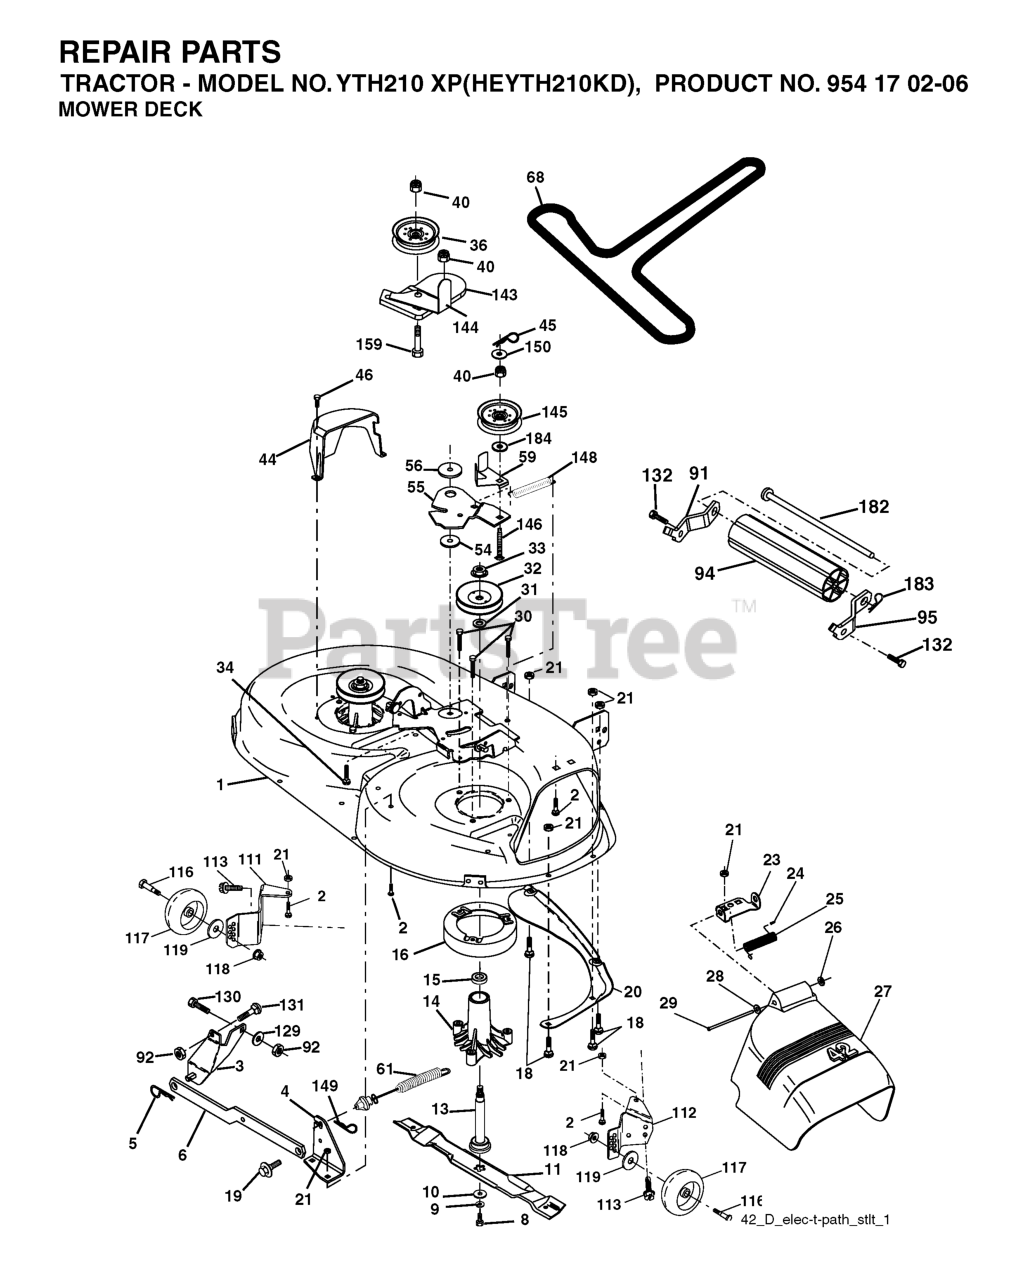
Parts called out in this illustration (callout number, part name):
1	42" DECK KIT
2	RP BOLT 5/16-18 X3/4 ZN/YEL GR
3	BRKT ASM SWAY BAR
4	BRACKET SWAY BAR 42" DECK
5	RETAINER-SPRNG RB
6	BAR SWAY DECK
8	BLADE BOLT
9	LOCKWASHER
10	WASHER.BLADE
11	42" HI-LIFT BLADE
13	SHAFT ASM VENT
14	HOUSING.MANDREL.VENTED (MACHD)
16	STRIPPER.MANDREL.ROUND.BLACK
18	BOLT
19	BOLT SHD 5/16-18
20	BAFFLE.VORTEX
21	LOCKNUT
23	BRKT, DEFL. MOWER
24	CAP-SLEEVE LT
25	SPRING TORSION
26	NUT PUSH M
27	SHIELD DEFLECTOR
28	Washer 11/32 x 5/8 x 16 Ga SD
29	ROD.HINGE
30	SCREW, WASHER HEAD
31	WASHER.SPACER.MANDREL
32	PULLEY/MANDREL
33	NUT, FLG TOPLOCK 9/16"
34	BOLT.3/8-16X1.50
36	FLAT IDLER PULLEY
37	WASHER
40	NUT LOCK FLG 3/8-16 UNC
44	GUARD MANDREL LH BLACK
45	RETAINER M
46	SCREW.1/4-20X5/8
55	ARM IDLER 42" MOWER LT/YT
56	SPACER.RETAINER.MOWER
59	GUARD, BELT
61	SPRING EXT ELEC CLUTCH
91	BRACKET ASM NOSEROLLER LH
92	NUT
94	NOSE ROLLER
95	BRACKET ASM NOSEROLLER RH
111	BRACKET, WHEEL
112	BRACKET, WHEEL
113	BOLT.5/16HEX.WHS.HD
116	BOLT M
117	WHEEL.GAUGE.STANDARD
118	LOCKNUT
119	WASHER.5/16.FLAT.STE.STD.
129	WASHER
131	BOLT D
132	SCREW, 3/8-16X3/4
143	BRACKET, ARM IDLER
144	DNO KEEPER.BELT.42".CLUTCH.CBL
145	PULLEY
146	BOLT, CARRIAGE IDLER BLACK
148	IDLER RETURN SPRING
149	SPRING.RETAINER.YELLOW.ZINC
182	ROD ROLLER NOSE STANDARD
183	SPRING RETAINER
184	WASHER
